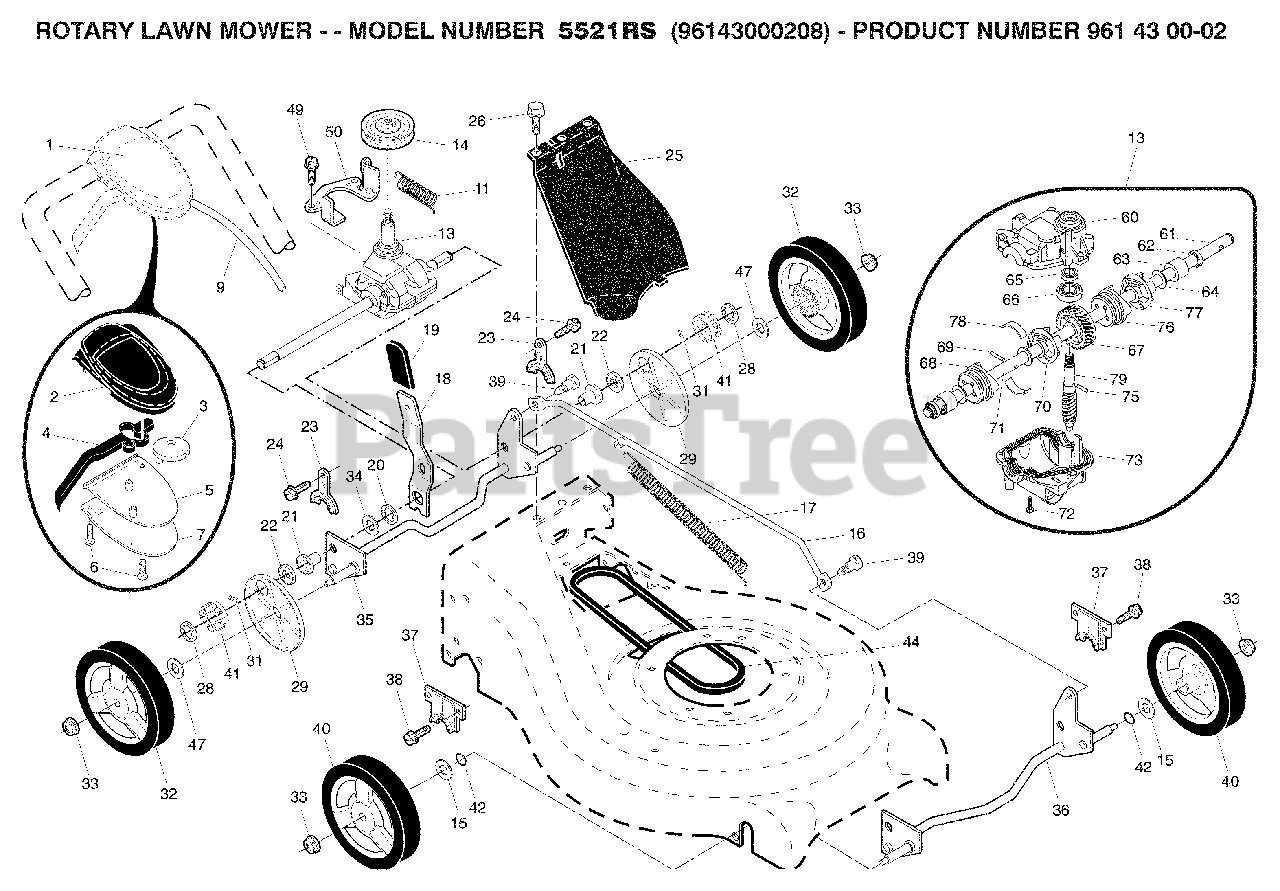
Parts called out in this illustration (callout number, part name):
1	Drive Control Assembly, Auto-Walk
2	Cover, Top, Auto-Walk Drive Control
3	Pulley
4	Lever, Auto-Walk Drive Control
5	Cover, Bottom, Auto-Walk Drive Control
6	Screw, Phillips Head #10 x 5/8
7	Plate, Trigger, Auto-Walk Drive Control
9	Cable, Drive Control
11	Spring, Return
13	Gear Case Assembly
14	Pulley, Drive
15	Washer, Flat
16	Rod, Connecting
17	Spring, Extension
18	Spring Selector
19	Knob, Selector Spring
21	Bearing, Support
22	Bearing, Ball
23	Retainer, Drive Assembly, Stamped
24	Screw, Tapping, Hex Head 1/4-20 x 3/4
25	Cover Drive
26	Screw, Threaded, Rolled #10-25 x 1/2
28	E-Ring 7/16
29	Cover, Dust, Wheel
31	Seal, Friction
32	Wheel & Tire Assembly, Rear
33	Nut, Hex, Flangelock 3/8-16
35	Shaft Assembly, Rear
36	Shaft Assembly, Front
37	Retainer, Front Shaft
38	Screw #12 x 5/8
39	Bolt, Shoulder, Semi-Gimlet Point
40	Wheel & Tire Assembly, Front 8 x 1-3/4
47	Washer 1/2 x 1-1/2 x .134
49	Screw, Hi-Lo Thread
50	Belt Keeper
60	Case, Upper
61	Shaft, Output, Long
62	Seal, Output Shaft
65	Seal, Worm Shaft
66	Bearing, Ball
67	Gear, 28 Teeth
68	Fixed Dog Clutch, LH
69	Pin, Output Shaft
70	Movable Dog Clutch, LH
71	Shaft, Output, Short
72	Screw, Case
73	Case, Lower
75	Pin, Worm Shaft
76	Movable Dog Clutch, RH
77	Fixed Dog Clutch, RH
78	Spring, Leaf
79	Shaft, Worm
